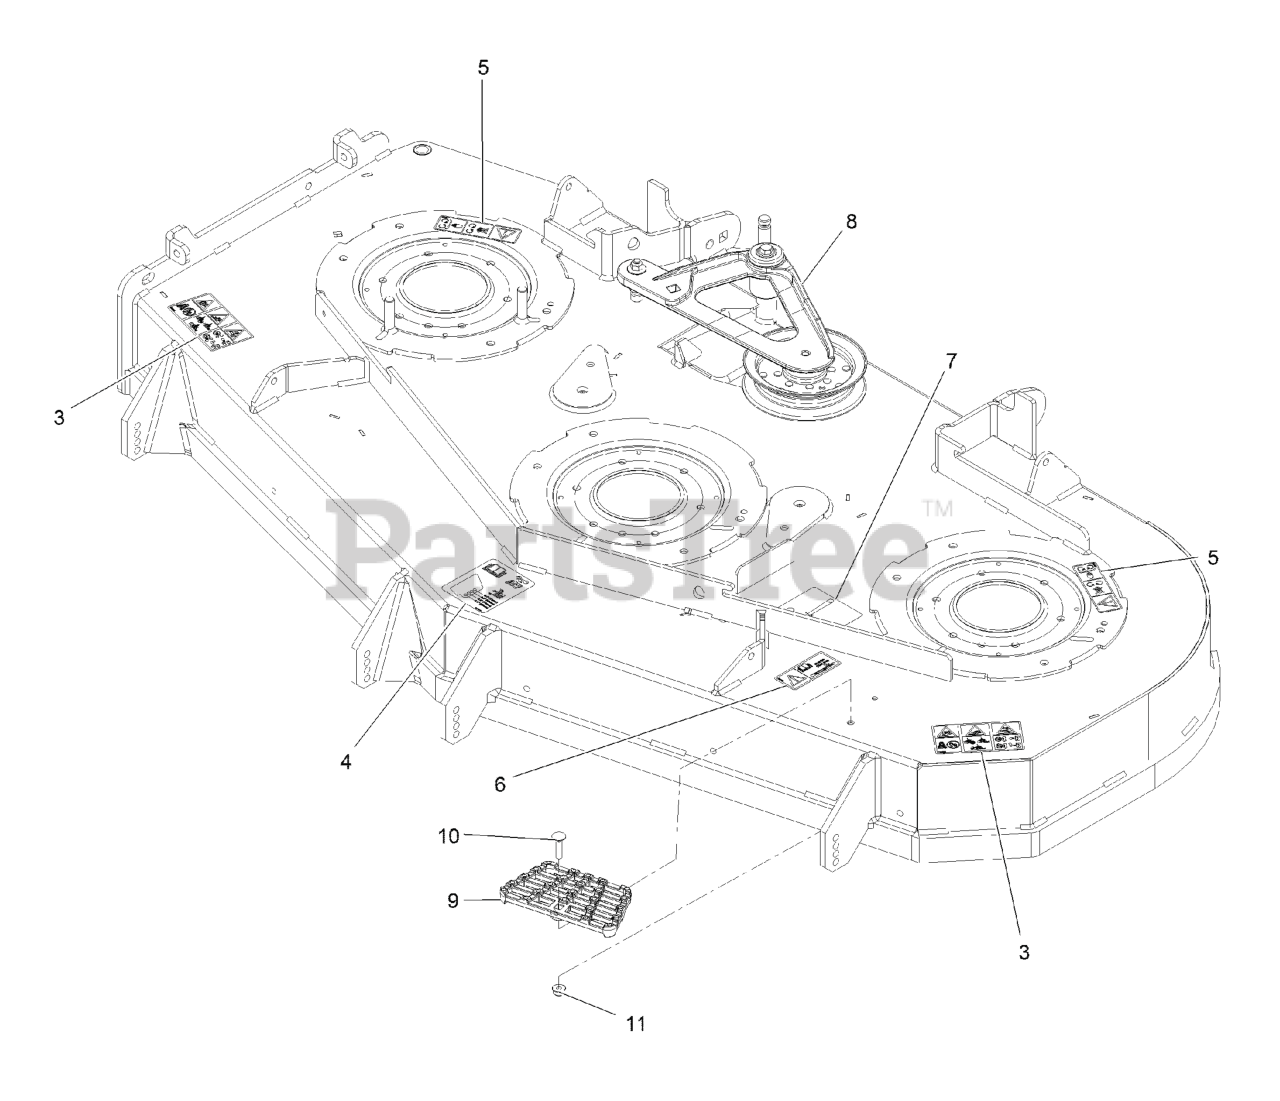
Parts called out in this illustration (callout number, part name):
3	DECAL-DANGER THROWN OBJECTS
4	DECAL-ROLLER, ANTI-SCALP
5	DECAL-COVER, MISSING
6	DECAL-BOLT TORQUE
7	DECAL-BELT ROUTING
8	DECK IDLER ASM
9	STEP-DECK
10	Bolt-Carriage 5/16-18 X 1 1/4
11	NUT-HF, NI
